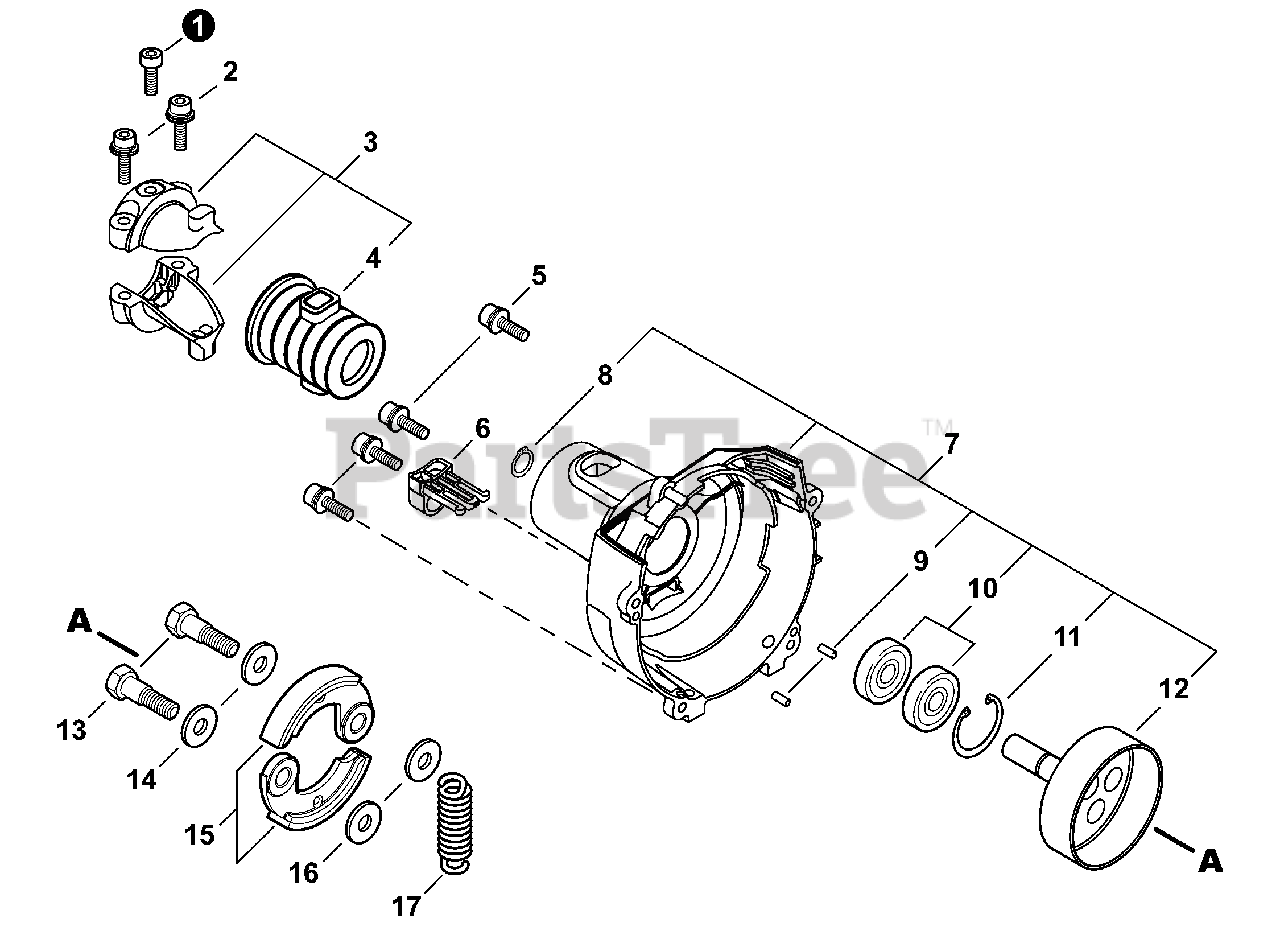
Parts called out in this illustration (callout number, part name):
1	BOLT 5×12
2	BOLT 5×25
3	HOLDER KIT, MAIN PIPE
4	CUSHION
5	BOLT 4×16
7	COVER ASSY, FAN
8	RING, RETAINING - 12
9	PIN, LOCATING 4
10	BEARING, BALL 6001
11	RING, SNAP 28
12	DRUM, CLUTCH
13	BOLT, CLUTCH 8×7.9×M6
14	WASHER, SPRING 8.5×16×0.5
15	SHOE, CLUTCH
16	WASHER 6.2×19×1.0
17	SPRING, CLUTCH
